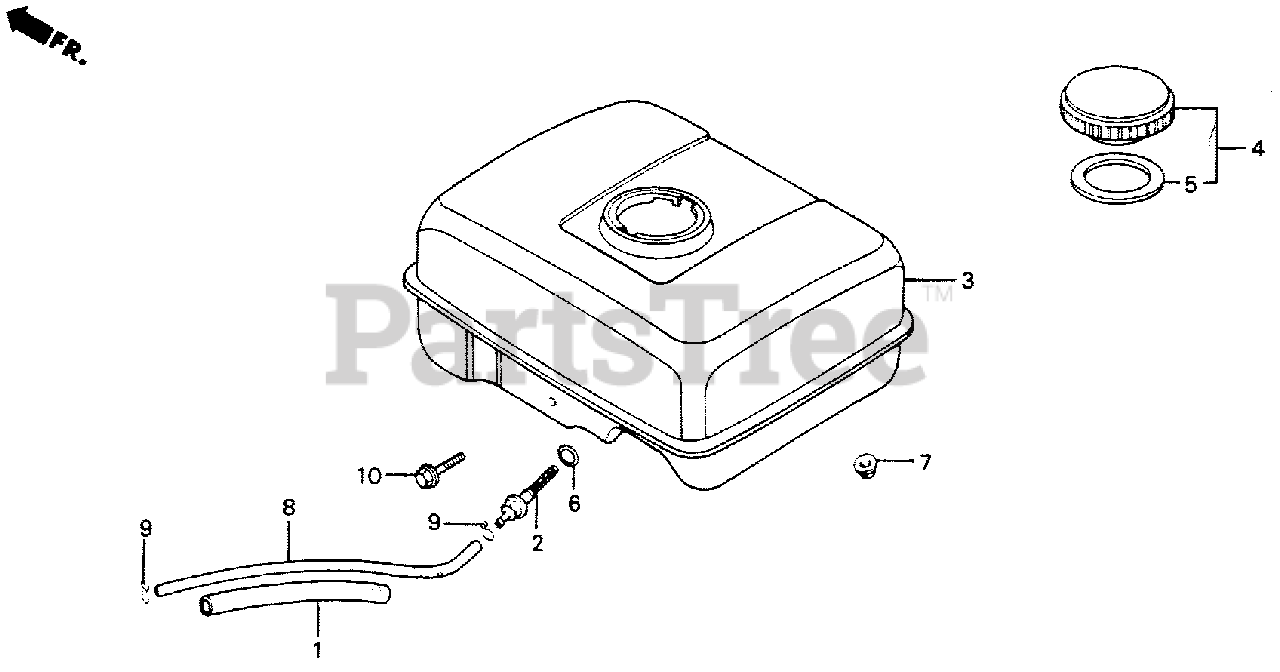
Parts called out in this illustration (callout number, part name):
1	RUBBER, SUPPORTER (107MM)
2	JOINT, FUEL TANK
3	TANK, FUEL *NH31* (MCKINLEY WHITE)
4	CAP, FUEL FILLER
5	GASKET, FUEL FILLER CAP
6	O-RING (13.5X1.5) (ARAI)
7	NUT, FLANGE (6MM)
8	BULK HOSE, FUEL (4.5X3000) (4.5X140)
9	CLIP, TUBE (B8)
10	BOLT, FLANGE (6X25)
